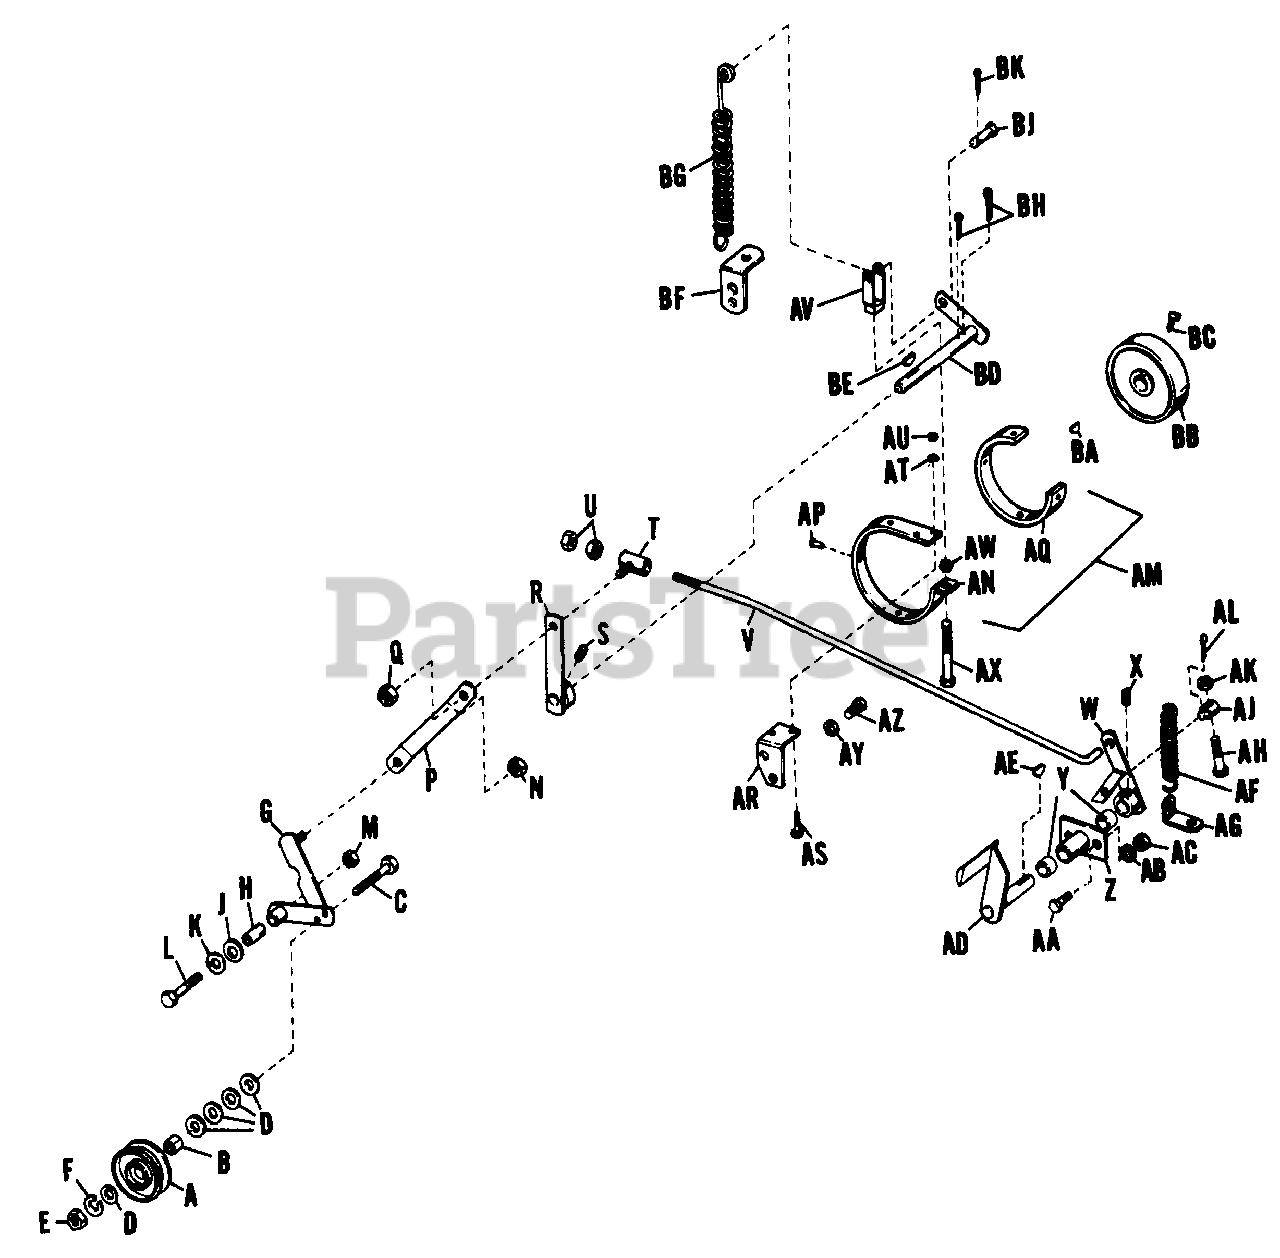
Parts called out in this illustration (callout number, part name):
A	Pulley, Idler
C	Screw, Cap, Hex., 3/8"-16 N.C. x 1-3/4" lg.
D	Washer, Plain, 3/8"
E	Nut, Hex., Full, 3/8"-16 N.C.
F	Washer, Lock, 3/8"
G	Lever Assembly, Idler
J	Washer, Plain, 3/8"
K	Washer, Lock, 3/8"
L	Screw, Cap, Hex., 3/8"-16 N.C. x 2-1/4" lg.
M	Nut, Hex., Full, 3/8"-16 N.C.
N	Nut, Lock, Hex., Full, 3/8"-16 N.C.
P	Link, Clutch
Q	Nut, Lock, Hex., Full, 5/16"-18 N.C.
R	Lever Assembly, Clutch and Brake
S	Screw, Set, Cup Point Socket Head, 5/16"-18 N.C. x 1/4" lg.
T	Guide Assembly, Rod
U	Nut, Hex., Full, 5/16"-18 N.C.
V	Rod, Brake and Clutch
W	Lever Assembly, Foot Pedal
X	Screw, Set, Cup Point Socket Head, 5/16"-18 N.C. x 1/4" lg.
Z	Bearing Assembly, Foot Pedal
AA	Screw, Cap, Hex., 5/16"-18 N.C. x 1" lg.
AB	Washer, Lock, 5/16"
AC	Nut, Hex., Full, 5/16"-18 N.C.
AD	Pedal Assembly, Foot (Brake and Clutch)
AE	Key, Woodruff #6
AG	Clip, Spring
AH	Screw, Cap, Hex., 3/8"-16 N.C. x 3" lg.
AK	Nut, Hex., Full, 3/8"-16 N.C.
AL	Pin, Cotter, 3/32" dia. x 3/4" lg.
AM	Brake Band and Lining Assembly
AN	Band, Brake
AP	Rivet #7 x 5/16" lg.
AQ	Lining, Brake
AR	Bracket, Brake Band
AS	Screw, Cap, Hex., 1/4"-20 N.C. x 3/4" lg.
AT	Washer, Lock, 1/4"
AU	Nut, Hex., Full, 1/4"-20 N.C.
AV	Clevis, Adj.
AW	Nut, Hex., Full, 3/8"-16 N.C.
AX	Screw, Cap, Hex., 3/8"-16 N.C. x 3-1/4" lg.
AY	Washer, Lock, 3/8"
AZ	Screw, Cap, Hex., 3/8"-16 N.C. x 7/8" lg.
BA	Key, Woodruff #9
BB	Drum, Brake
BC	Screw, 5/16" Cup Point Square Head, 5/16"-18 N.C. x 5/8" lg.
BD	Shaft Assembly, Clutch and Brake
BE	Key, Woodruff #6
BF	Retainer, Spring
BH	Pin, Cotter 1/8" x 1-1/4" lg.
BJ	Pin, Clevis
BK	Pin, Cotter, 3/32" x 3/4"lg.
